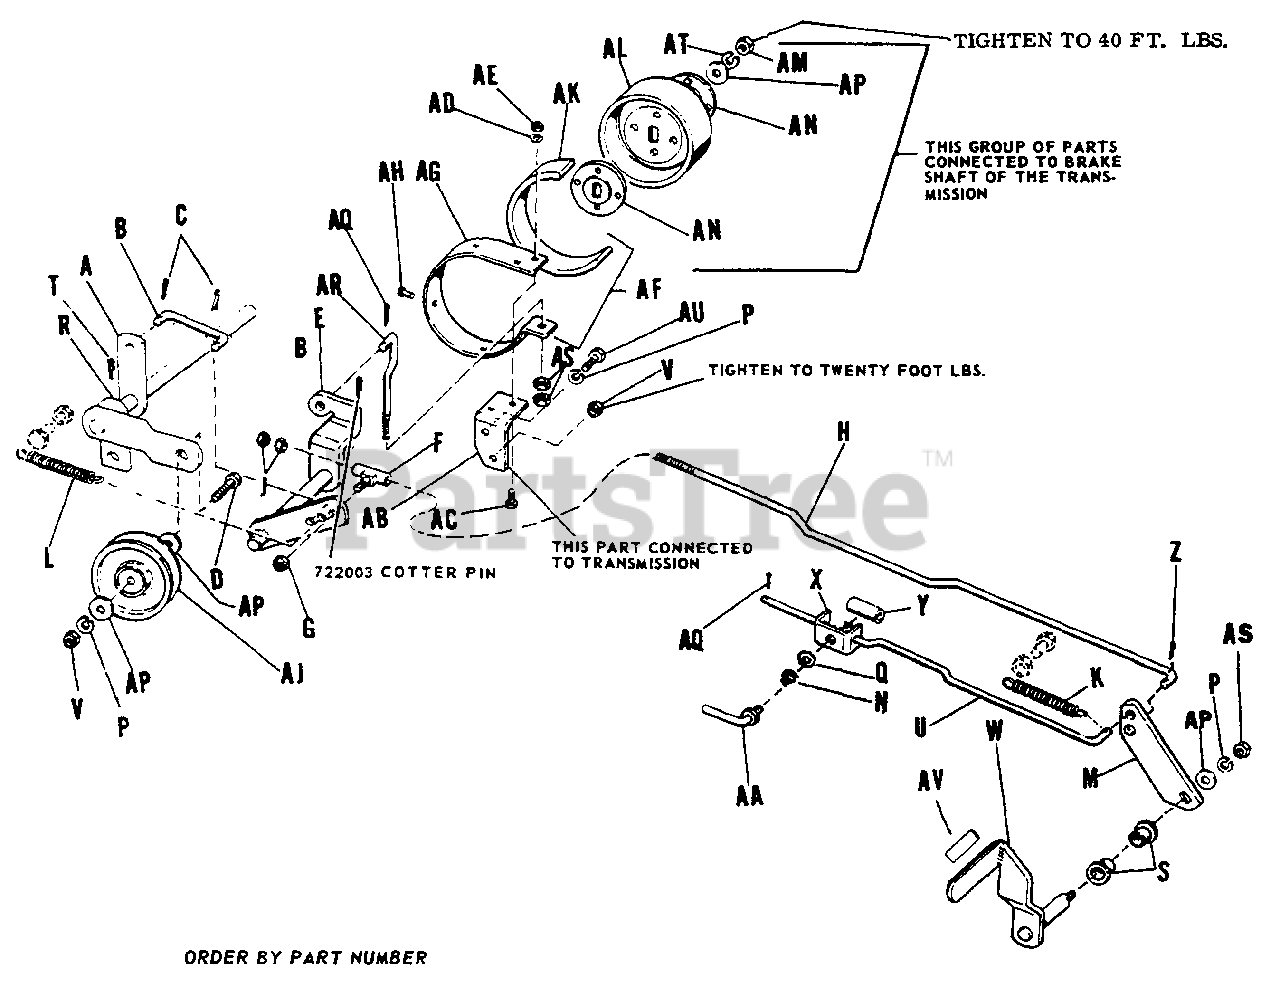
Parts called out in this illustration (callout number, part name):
A	Idler Pivot Assembly
B	Clutch Lever Link
C	Cotter Pin, 3/32 x 3/4" lg.
D	Hex. Cap Screw, 3/8"-16 x 1-1/4"
E	Pivot Lever Assembly
F	Rod Guide Assembly
G	Full Lock Hex. Nut, 5/16"-18
H	Brake & Clutch Rod
J	Full Hex. Nut, 5/16"-18
K	Tension Spring
L	Tension Spring
M	Pedal Foot Arm
P	Lock Washer, 3/8"
Q	Plain Washer, 7/16"
R	Bar Pivot
T	Cotter Pin 1/8 x 3/4" lg.
U	Brake Rod
V	Full Hex. Nut, 3/8"-16
W	Foot Pedal Assembly
X	Bracket Assembly
Z	Cotter Pin, 1/8 x 3/4" lg.
AA	Park Brake Lock
AB	Brake Band Bracket
AC	Hex. Cap Screw, 1/4"-20 x 3/4"
AD	Lock Washer, 1/4"
AE	Full Hex. Nut, 1/4"-20
AF	Brake Band & Lining Assembly
AH	Rivet #7 x 5/16"
AJ	Idler Pulley
AK	Brake Lining
AL	Brake Drum
AM	Full Hex. Nut, 7/16"-14
AN	Special Washer
AP	Plain Washer, 3/8"
AQ	Cotter Pin, 3/32 x 3/4"
AR	Brake Rod
AS	Full Hex. Nut, 3/8"-16
AT	Lock Washer, 7/16"
AU	Hex. Cap Screw 3/8"-16 x 7/8" lg.
AV	Pad, Pedal
